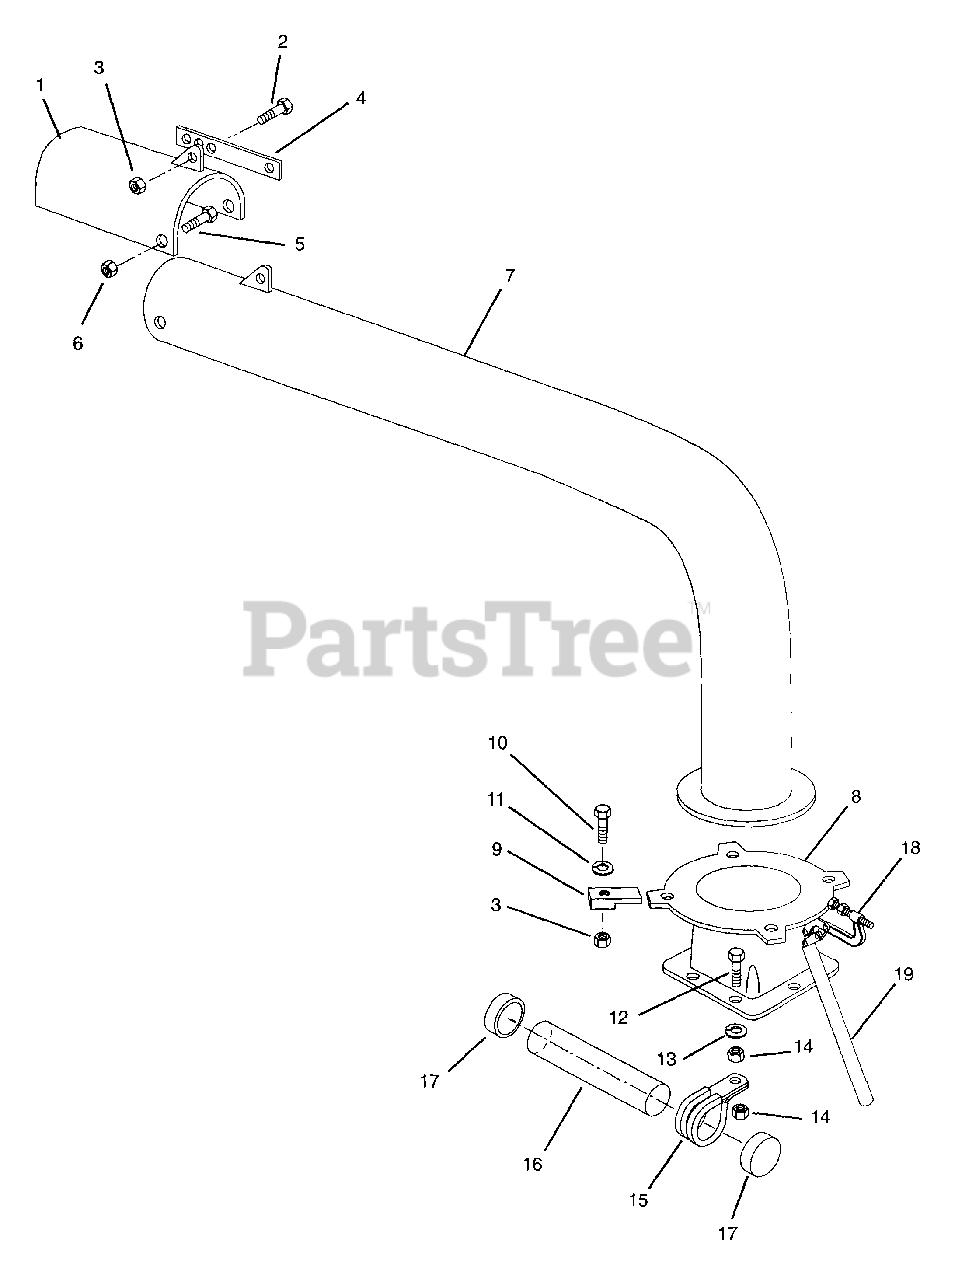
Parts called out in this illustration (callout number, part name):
1	Deflector
2	Bolt-Hex .31-18 x 1.00-Grade 5
3	Nut-Locking-Center .31-18
4	Deflector Arm
5	Bolt-Hex .38-16 x 1.00
6	Nut-Locking-Top .38-16
7	Discharge Chute
8	Discharge Neck
9	Clamp
10	Bolt-Hex .31-18 x .88-Grade 5
11	Washer-Locking .31 x .078
12	Bolt-Hex .25-20 x 1.00-Grade 5
13	Washer-Lock .25 x .077
14	Nut .25-20
15	Clamp 2.00 Dia. x .265 ID
16	Plastic Tube-Instructions
17	End Cap-Instruction Tube
19	Pipe Handle
